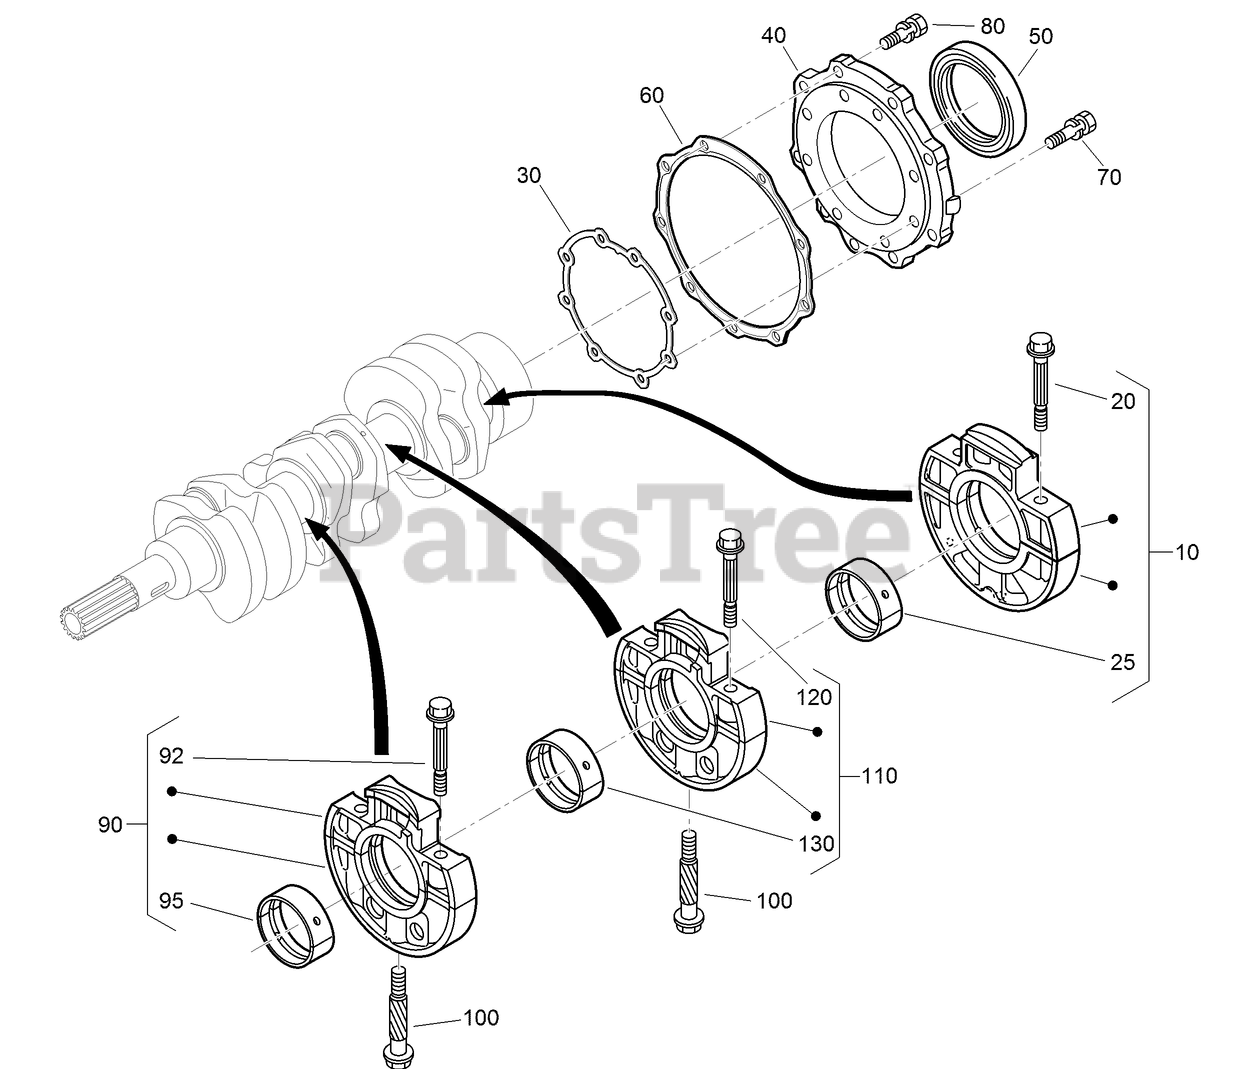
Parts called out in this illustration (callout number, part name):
10	WHEEL BEARING CASE ASM
20	BOLT-CASE, BEARING
25	METAL-CRANKSHAFT (STD)
25	METAL-CRANKSHAFT (0.2MM)
25	METAL-CRANKSHAFT (-0.4MM)
30	GASKET-CASE, BEARING
40	COVER-CASE, BEARING
50	SEAL-OIL
60	GASKET-COVER, CASE
90	MAIN BEARING CASE ASM
92	BOLT-CASE, BEARING
95	METAL-CRANKSHAFT
100	BOLT-CASE, BEARING
110	MAIN BEARING CASE ASM
120	BOLT-CASE, BEARING
130	METAL-CRANKSHAFT
